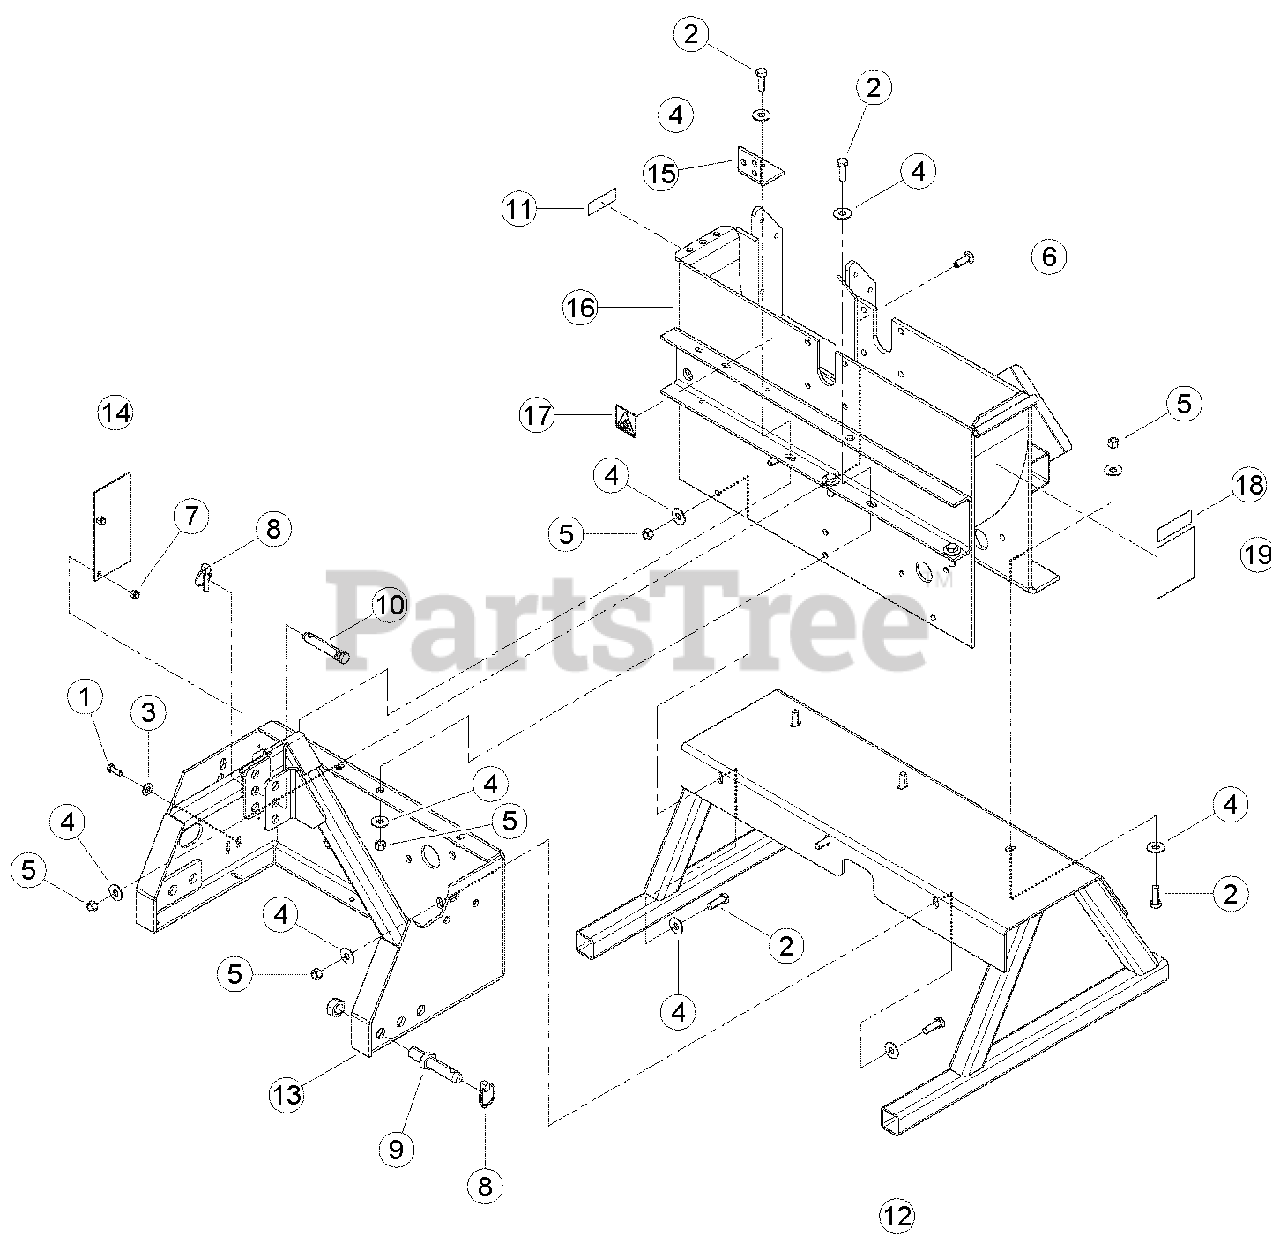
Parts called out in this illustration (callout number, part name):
1	BOLT, 3/8 X 1 HEX HD GR5 ZP
2	BOLT, 1/2 X 1-1/2 HEX HD GR5 ZP
3	WASHER, 3/8 FLAT ZP
4	WASHER, 1/2 FLAT ZP
5	NUT, 1/2 CENTERLOCK GRB ZP
6	BOLT, 1/2 X 1-1/2 CRG GR5 ZP
7	NUT, 3/8 NE NYLOCK ZP
8	PIN, 7/16 X 1-3/4 LYNCH
9	PIN, LIFT ARM 7/8 X 5 LONG
10	PIN, TOP LINK 3/4 X 4-1/2 LONG
11	DECAL, SERIAL NUMBER
12	WELDMENT, PTO STAND
13	WELDMENT, HITCH SUPPORT
14	COVER, HOSE ACCESS
15	ANGLE, LOWER SHOCK
16	ASSEMBLY, CH8540 BOTTOM HOUSING, SERVICE PART
17	DECAL, SHIELD DANGER ISO
18	DECAL, 71854S INFORMATION
19	DECAL, 112 DB
